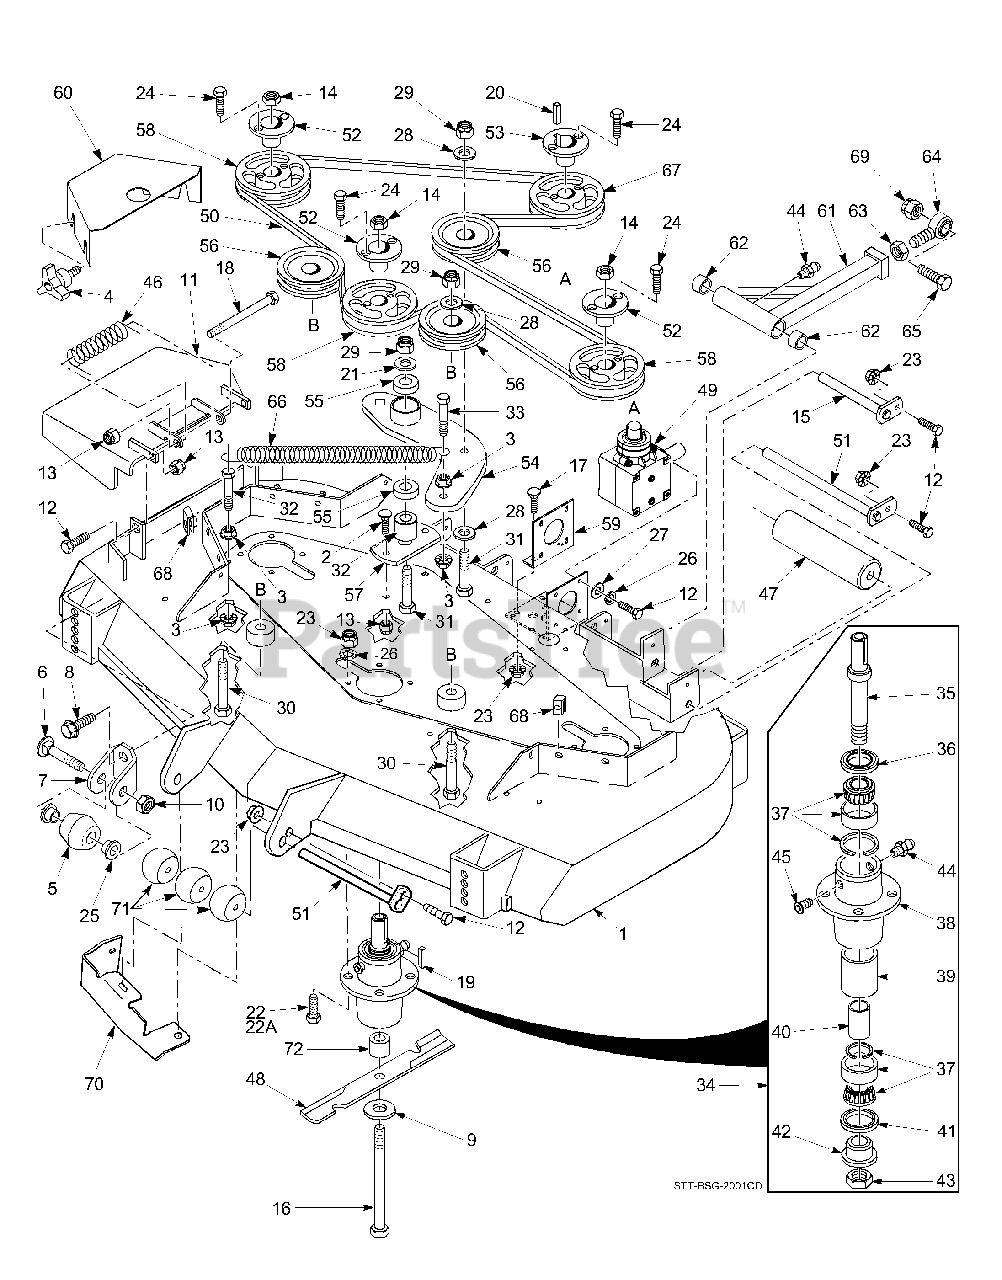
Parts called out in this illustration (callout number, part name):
1	Cutter Deck, 61" Advantage
1	Cutter Deck, 72" Advantage
2	Bolt, Carriage 5/16-18 x 1"
3	Nut, Hex Serrated Flange 3/8-16
4	Wing nut, 3/8-16
5	Anti-Scalp Wheel
6	Bolt, Carriage 3/8-16 x 4"
7	Anti-Scalp Wheel Bracket
8	Bolt, Hex Serrated Flange 3/8-16 x 1"
9	Flatwasher, 5/8" (.688 x 1.75 x .134)
10	Locknut, 3/8-16 Center Lock
11	Discharge Chute, 61" & 72" Adv.
12	Bolt, Hex Head 5/16-18 x 1.75" (Front)
13	Nut, Hex Elastic Stop 5/16-18
14	Nut, 5/8-11 UNC
15	Push Arm Shaft
16	Bolt, Hex Head 5/8-11 x 9.50"
17	Bolt, Carriage 5/16-18 x .75"
18	Bolt, Hex Head 5/16-18 x 4.75"
19	Key, 1/4 x 1/4 x 2"
20	Key, 1/4 x 1/4 x 1.25"
21	Flatwasher,3/8-.39 x .938 x .105 HD
22	Bolt, Hex Head 5/16-18 x 1.50"
22A	Bolt, Hex Head 5/16-18 x 1.75"
23	Nut, Hex Serrated Flange 5/16-18
24	Bolt, Hex Head 1/2-20 x .75"
25	Bushing, .376 I.D. Oilite
26	Lockwasher, 5/16"
27	Flatwasher, 5/16" (.375 x .875 x .083)
28	Flatwasher, 3/8" (.391 x .938 x .105)
29	Nut, Hex Elastic Stop 3/8-16
30	Bolt, Hex Head 3/8-16 x 3.25"
31	Bolt, Hex Head 3/8-16 x 2.50"
32	Pivot, Idler - Short
33	Bolt, Hex Head 3/8-16 x 1.50" Grade 8
34	Spindle Assembly
35	Spindle Shaft
36	Seal, Top
37	Bearing Assembly
38	Spindle Housing
39	Spacer, Outside
40	Spacer, Inside
41	Seal, Bottom
42	Spindle Bushing, Bottom
43	Nut, Special 1 - 1/16-18
44	Grease Fitting
45	Relief Fitting, Tapered Spindle
46	Spring, Discharge Chute
47	Guide, Roller
48	Cutter Blade, 21.0" 61"
48	Cutter Blade, 24.5" 72"
49	Gearbox Assembly, Deck Drive
50	Belt, Cutter Deck Drive, 61"
50	Belt, Cutter Deck Drive, 72"
51	Roller Shaft
52	Tapered Hub, 1-1/8" Bore
53	Tapered Hub, 1" Bore
54	Idler Arm, Cutter Deck
55	Bearings, Ball
56	Pulley, Idler
57	Base, Idler Pivot
58	Pulley, 6.35 O.D. - 61"
59	Mounting Plate, Gearbox
60	Belt Cover, LH - 61"
61	Pusharm
62	Spacer
63	Nut, Hex Head 5/8-18 UNF
64	Rod End, 5/8" Male RH Thread
65	Bolt, Hex Head 5/8-11 x 4-1/2"
66	Spring, Cutter Deck
67	Pulley, 6.35 O.D. - 61"
68	U-Nut, 3/8-16
69	Nut, Hex Elastic Stop 5/8-11
70	Discharge Baffle 61"
71	Guide Roller
72	Spacer, Spindle
